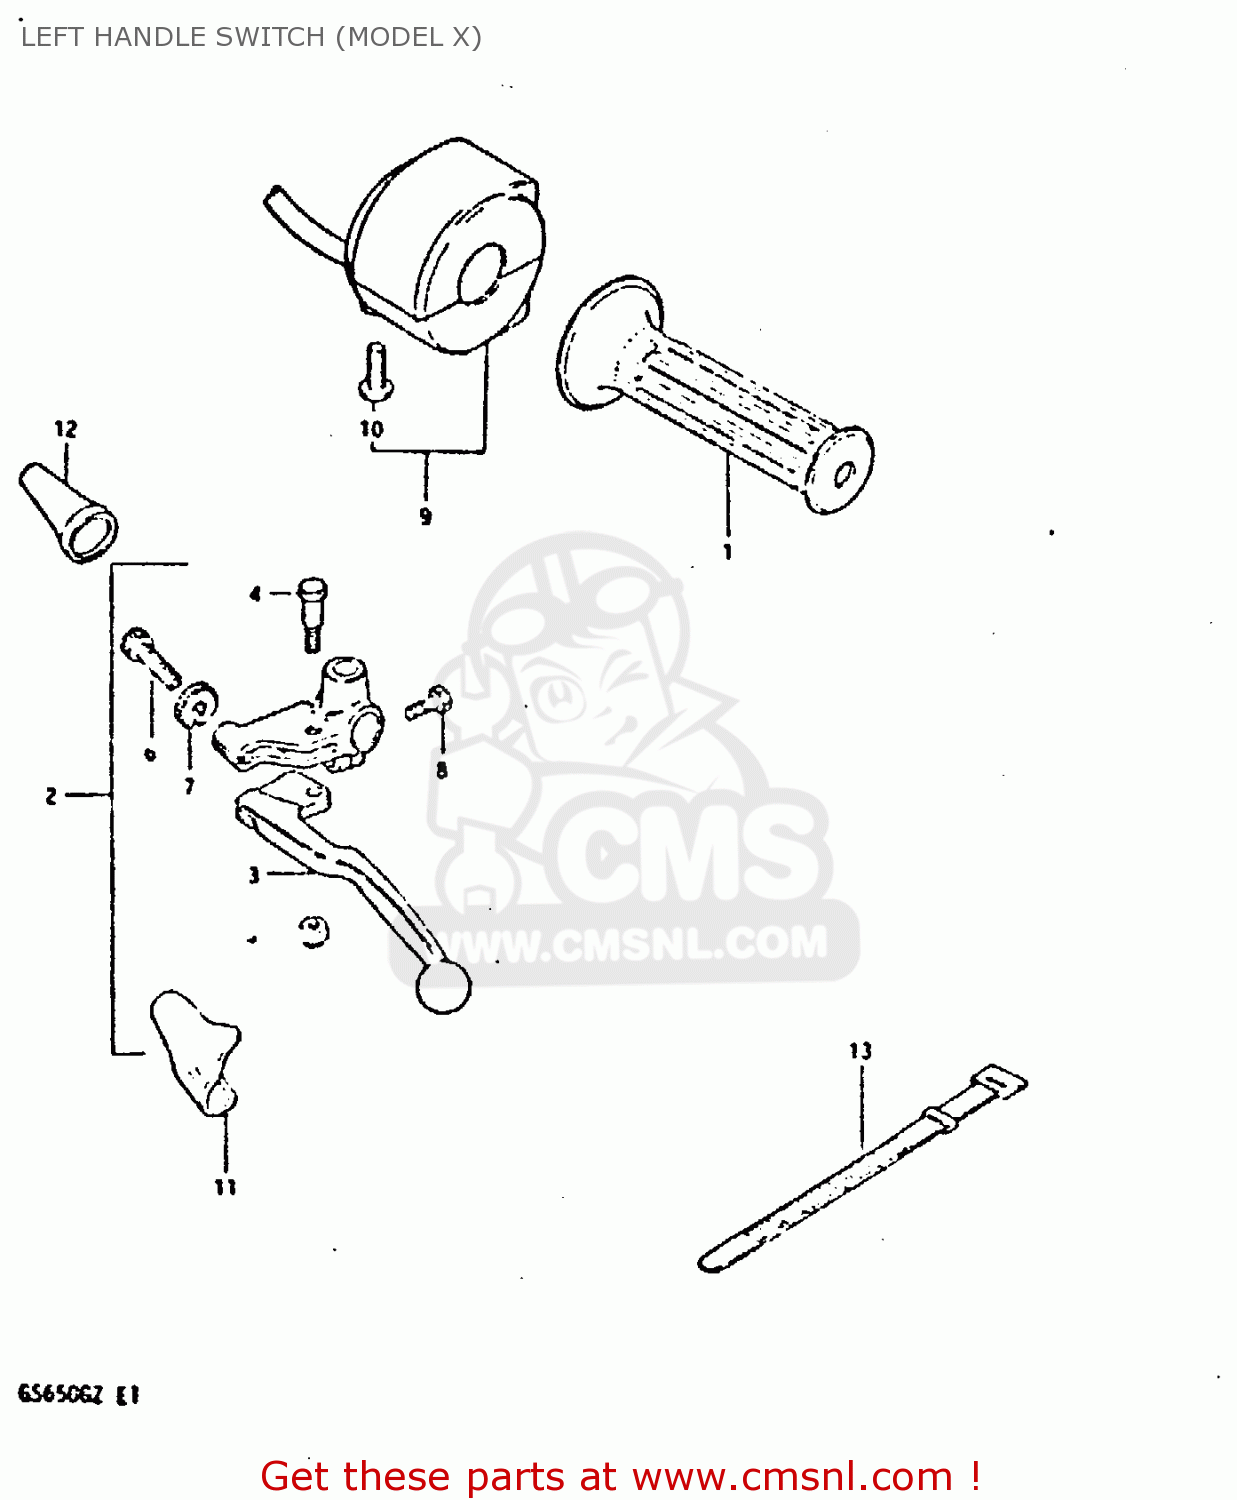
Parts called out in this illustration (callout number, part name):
1	GRIP,L
2	LEVER ASSEMBLY
3	LEVER,CLUTCH
4	BOLT,LEVER
5	NUT 6MM
6	ADJUSTER,CABLE
7	NUT,CABLE ADJUSTER
8	BOLT,CLUTCH LEVER HOLDER
9	SWITCH ASSY, HANDLE LH
10	SCREW
11	COVER,CLUTCH LEVER
12	BOOT,CLUTCH CABLE
13	CLAMP(L:120)
